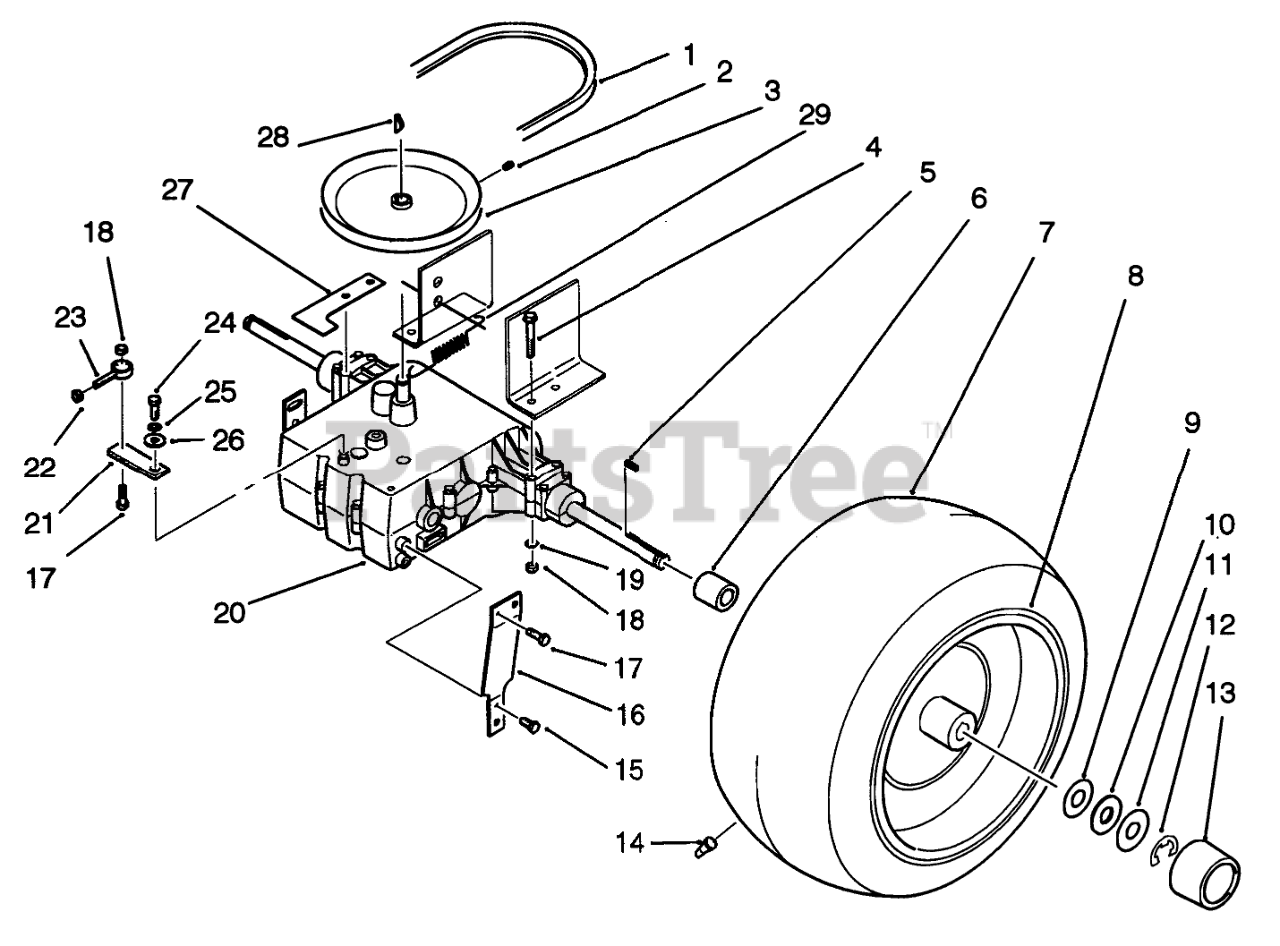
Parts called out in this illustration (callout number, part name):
1	BELT-V
2	SCREW-SQ HD SET
3	PULLEY-TRANS R
4	SCREW-HH
5	SQ KEY
6	LH AXLE SPACER
7	TIRE (20 X 10.00-10)
9	WASHER
10	WASHER-SHIM
11	WASHER-WHEEL
12	E-RING
13	HUB CAP-FLAT BLACK
14	VALVE
15	Screw
16	STRAP R
17	SCREW-HH
19	WASHER-PLAIN
20	ASS'Y-TRANS 5-SPEED
21	ARM-TRANS. R
22	Nut
23	BALL-END
24	SCREW-HH
25	WASHER-LOCK
26	WASHER
27	STOP-BRAKE R
28	KEY-HI-PRO
29	SPRING-EXTENSION
